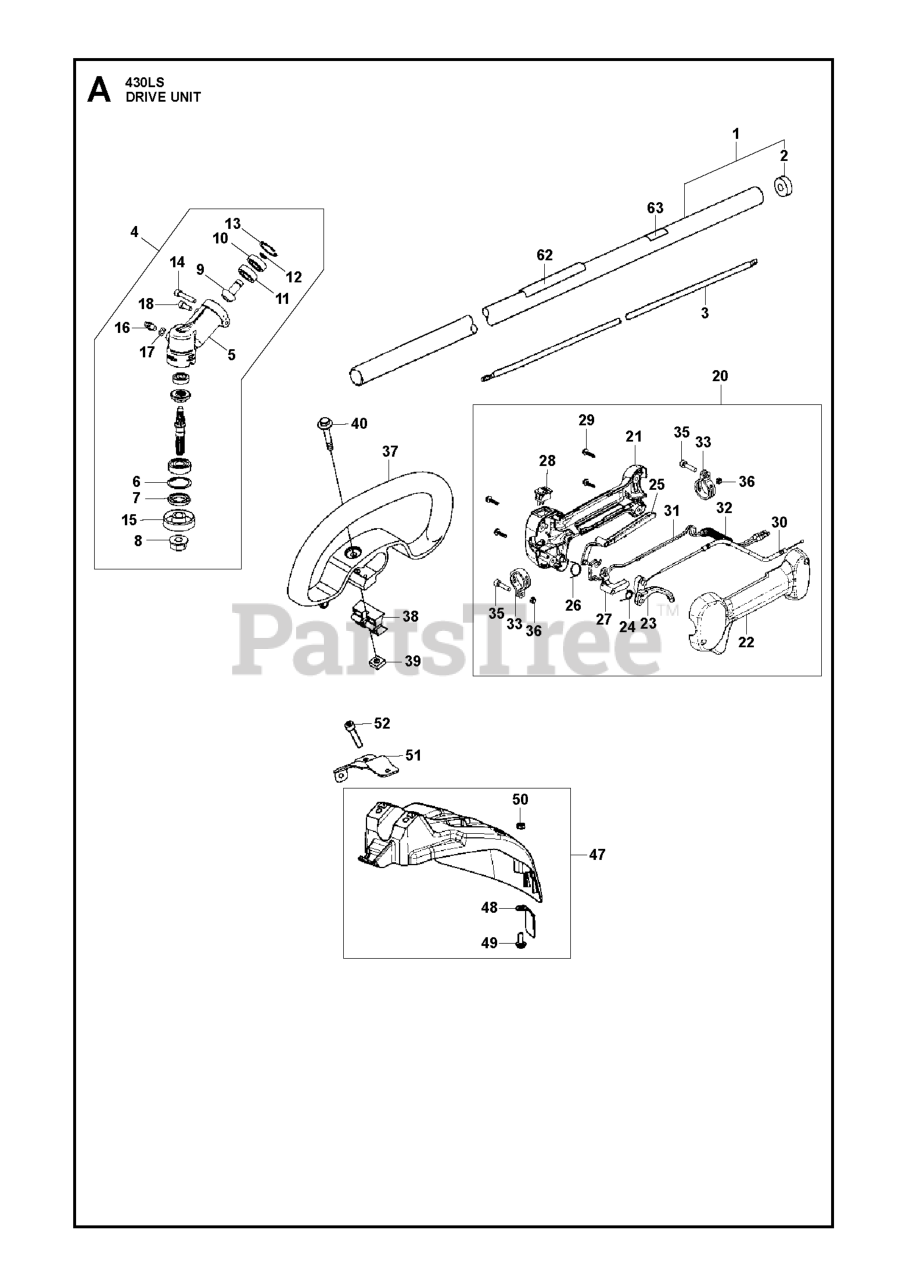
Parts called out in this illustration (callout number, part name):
4	RP_GEARCASE ASSY.
5	GEARCASE
6	RING,SNAP M26x1.2 RP-318013340
11	BALL BEARING
13	RP_RING
18	BOLT, TORX
21	BODY RIGHT
23	LEVER THROTTLE
24	SPRING, THROTTLE
25	SPRING, THROTTLE
26	LEVER SAFETY
27	LEVER JOINT
35	BOLT
36	NUT
37	RP HANDLE, LOOP
38	SPACER PLASTIC
40	BOLT
47	GUARD ASSY
50	NUT
52	BOLT, TORX
62	LABEL CAUTION
